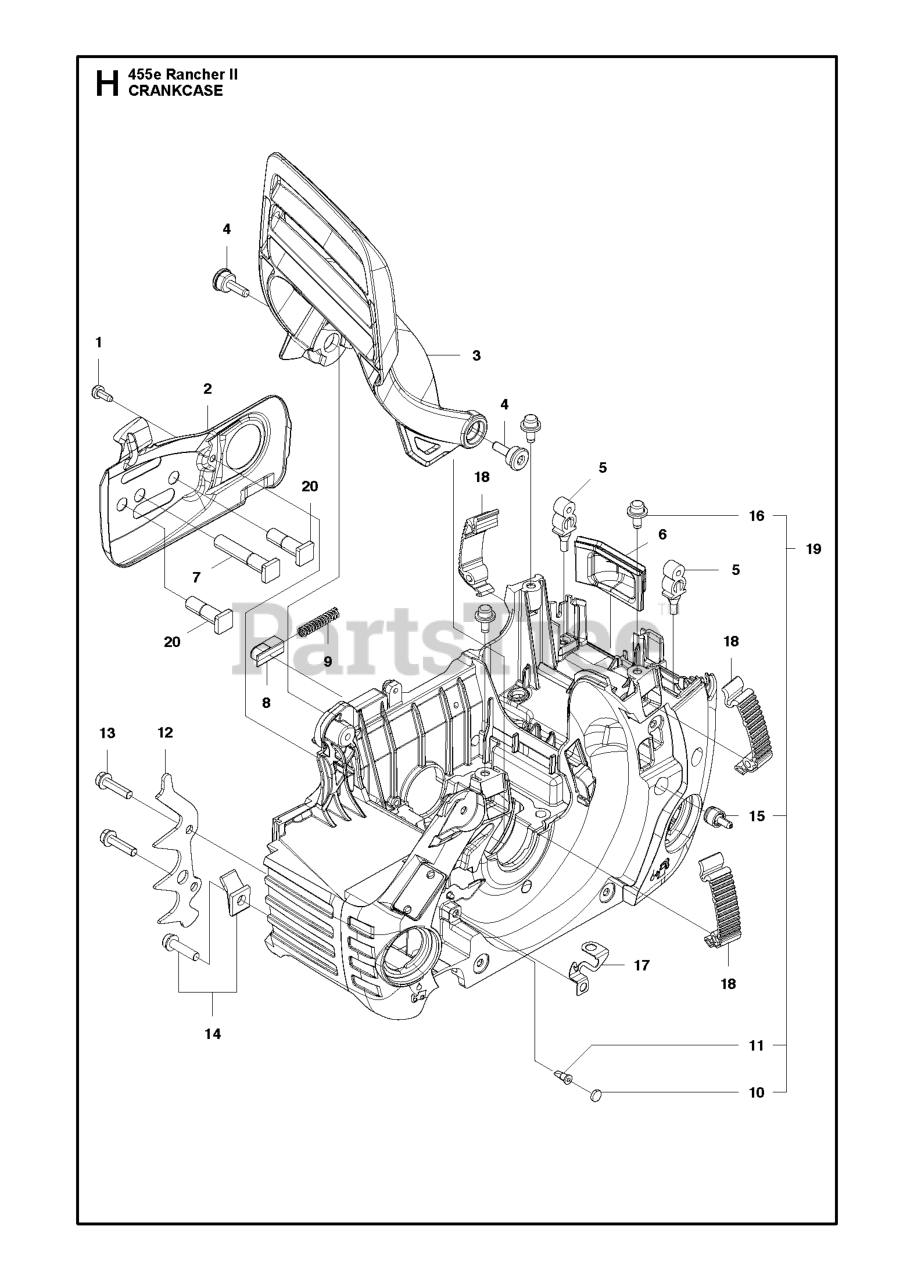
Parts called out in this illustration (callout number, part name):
1	SCREW
3	HAND GUARD
4	SCREW, HAND GUARD
5	SUPPORT
7	GUIDE BOLT (X2)
9	LOCK SPRING
10	PLUG
11	VALVE-CHECK (DUCKBILL)
13	SCREW IHSCFT
14	CHAIN CATCHER
15	FUEL TANK VENT
16	GUIDE PEN
17	GROUND PLATE
18	BUCKLE ORANGE
